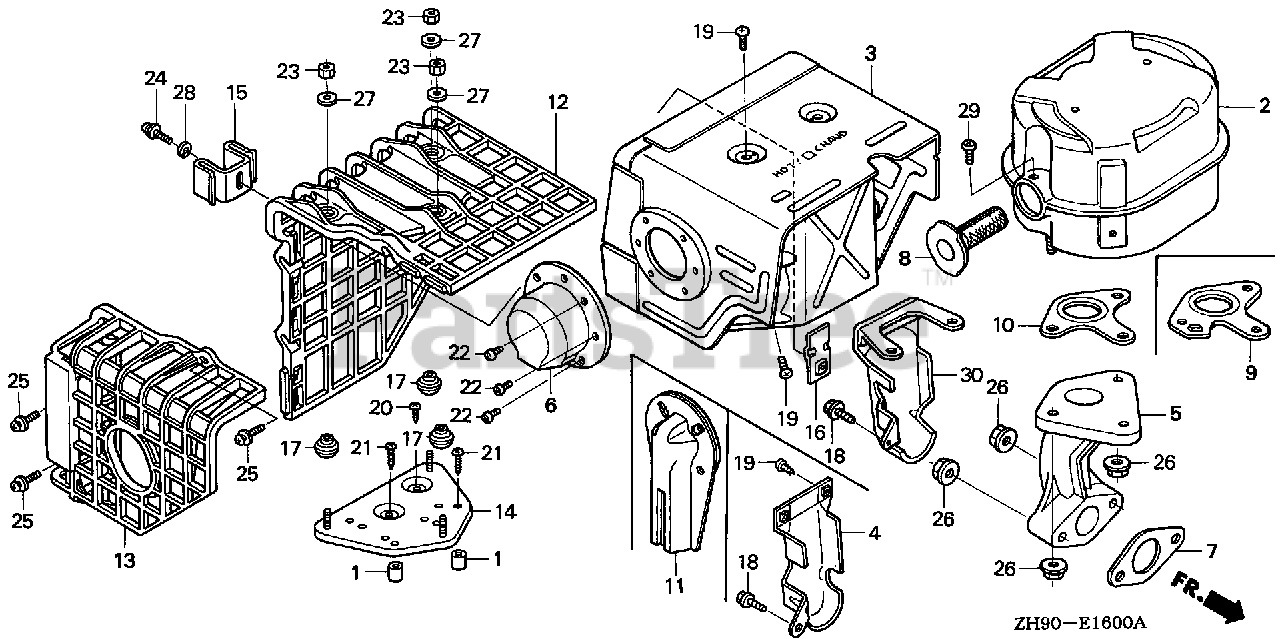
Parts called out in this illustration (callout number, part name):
2	MUFFLER
3	PROTECTOR, MUFFLER (STD)
4	PROTECTOR, EX. PIPE
6	CAP, MUFFLER
7	GASKET, EX. PIPE Use up to Engine SN 2949254.
7	GASKET, EX. PIPE (WACKER)
8	ARRESTER, SPARK
9	GASKET, MUFFLER (ARRESTER)
18	BOLT, FLANGE (6X12) (CT200)
19	SCREW, TAPPING (5X8)
22	SCREW, TAPPING (4X6) (TO INSTALL OPTIONAL SPARK ARRESTER)
26	NUT, FLANGE (8MM)
29	SCREW, TAPPING (4X6) (TO INSTALL OPTIONAL SPARK ARRESTER)
